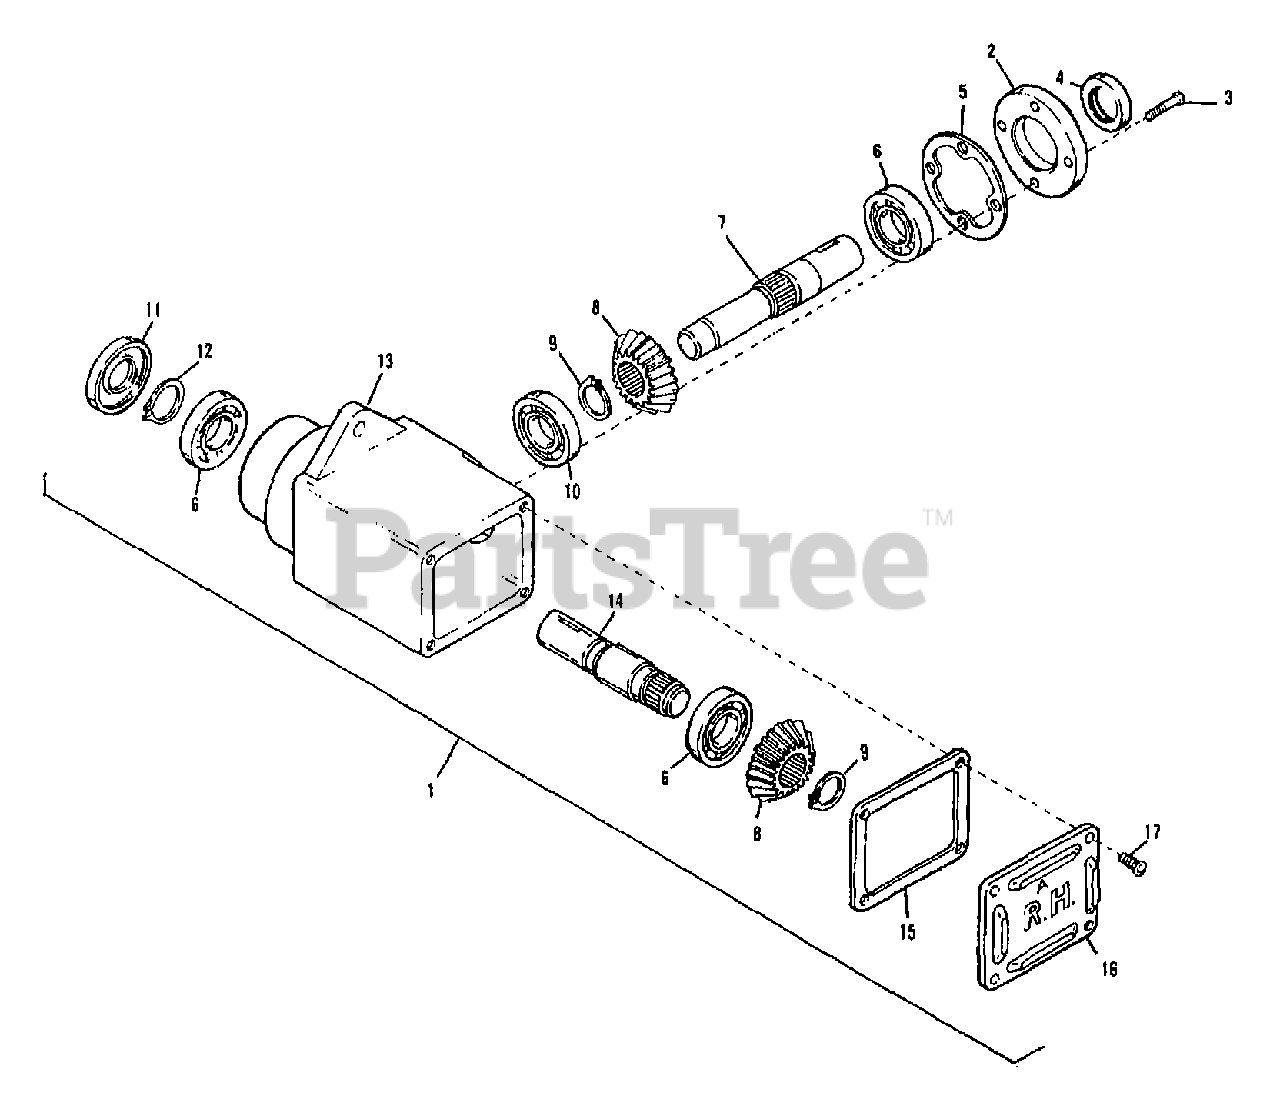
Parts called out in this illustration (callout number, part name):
1	HEAD ASSY
2	CAP & SEAL
4	OIL SEAL
6	BALL BEARING
7	SHAFT INPUT
8	MITER GEAR
9	RET RING
10	BALL BEARING
11	OIL SEAL
12	RET RING
14	OUTPUT SHAFT
15	GASKET
